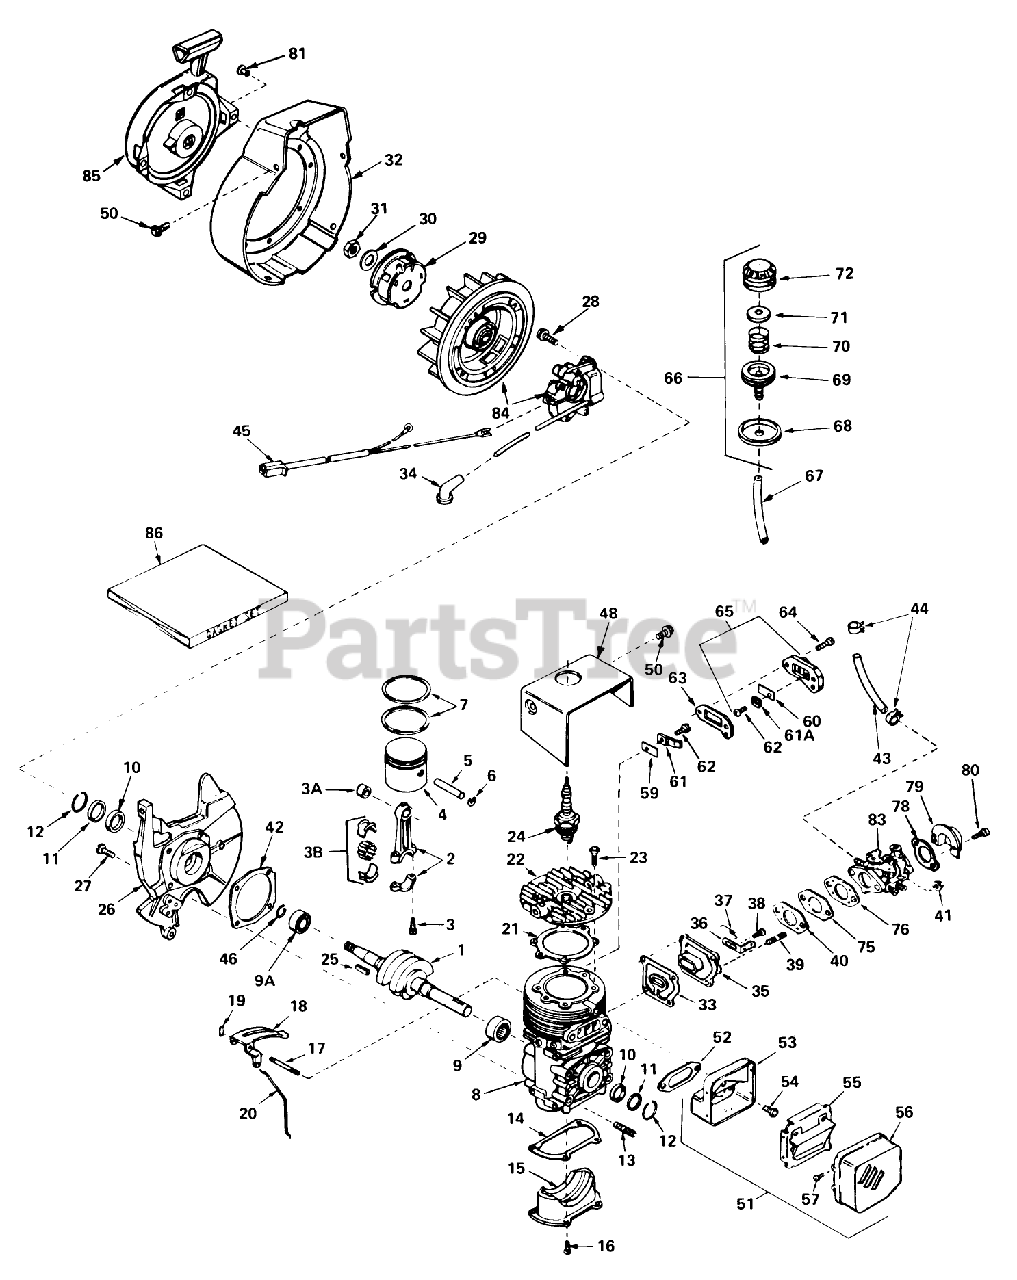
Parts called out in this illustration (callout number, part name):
1	Crankshaft
2	Rod Assembly, Connecting (Incl. #3, 3A 3B)
3	Bolt-Rod, Connecting
3A	Bearing-Cartridge
3B	Bearing Liner Set, Needle
4	Piston
5	Pin, Piston
6	Ring-Retaning
7	Ring Set
9	Bearing-Cartridge
9A	Bearing-Ball
10	Seal, Crankshaft
11	Retainer, Crankshaft Seal
12	Spring, Crankshaft Seal Retainer
14	Gasket, Cover
15	Plate, Cover
16	Screw (T-25, 10-24 x 1/2)
17	Shaft, Air Vane
18	Vane Assy., Air
19	Clip,Air Vane
20	Link, Governor
21	Gasket, Head
23	Screw (T-30, 1/4-20 x 3/4)
24	Head Adjustment Knob
25	Key, Flywheel
26	Base Assy., Housing (Incl. Nos. 29, 30 31)
27	Screw
28	Screw, Hex Washer Hd.
29	Starter Cup
30	Washer-Spring
31	Nut-Flywheel
32	Housing, Blower
33	Gasket, Port
34	Cover-Spark Plug
35	Adapter, Cover
36	Lever, Adjusting
37	Spring, Governor
38	Screw
40	Gasket, Carburetor 1/8" thick)
41	Locknut
42	Gasket, Shroud Base
43	Line-Fuel (8.62)
44	Clamp-Line, Fuel
45	Harness, Wire
46	Ring, Retaining
48	Shroud, Cylinder
50	Screw-Hex, Hd.
51	Muffler Assembly (Incl. #53-57)
52	Gasket-Muffler
53	Base-Muffler
54	Screw
55	Baffle, Muffler
56	Cover, Muffler
57	Screw
59	Reed, Compression Release
60	Reed, Compression Release
61	Plate, Reed Hold Down
61A	Plate, Reed hold down
62	Screw
63	Gasket, Compression Release
64	Screw
65	Cover Assy., Compression release (Incl. Nos. 60, 61A 62)
66	Primer Assy. (Incl. Nos. 67 thru 72)
67	Line, Primer
68	Retainer, Primer Bulb
69	Body, Primer
70	Spring, Primer Bulb
71	Washer, Primer Bulb
72	Bulb, Primer
75	Spacer
76	Gasket, Carburetor (1/16"thick)
78	Gasket
79	Baffle-Carburetor
80	Screw
81	Rivet, Pop (3/16" dia.)(Can be purchased locally)
83	Carburetor (Incl. No. 76)
84	Magneto
85	Starter-Rewind
86	Gasket Set (Incl. items marked *)
